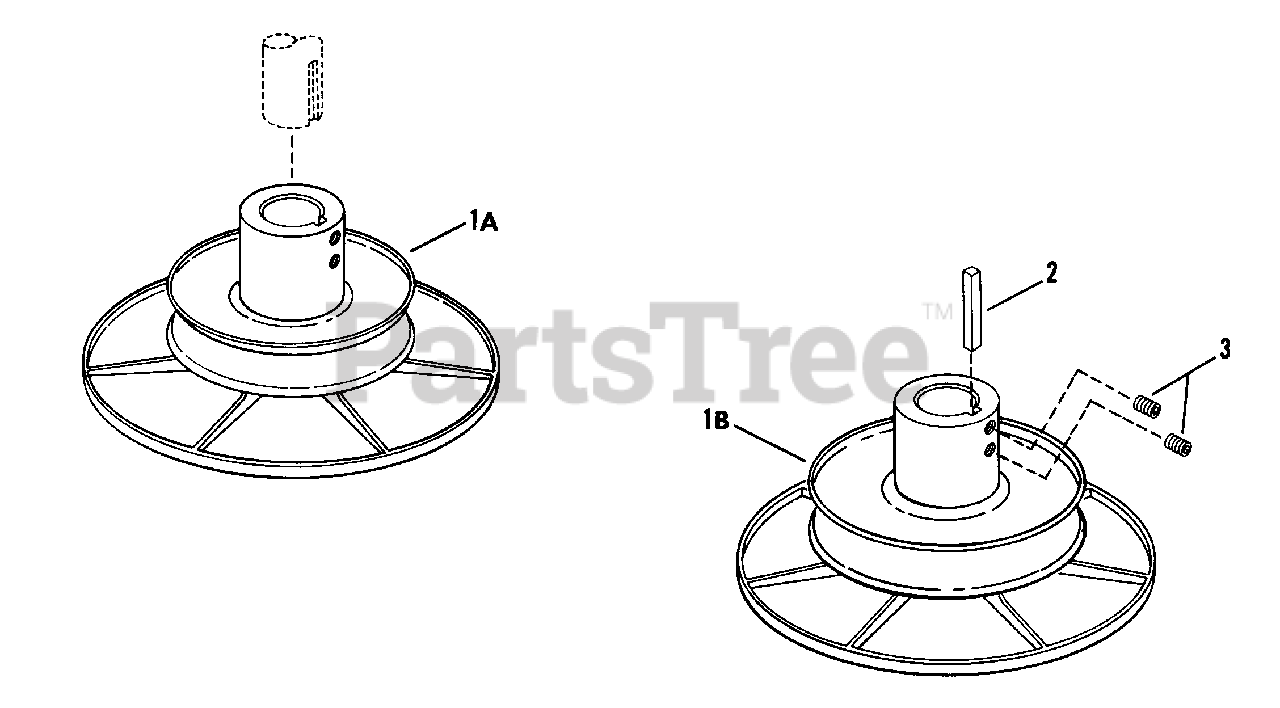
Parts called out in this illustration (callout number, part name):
1A	ASSEMBLY, Drive Disc, 4" O.D. for 30 & 33" Models
1B	ASSEMBLY, Drive Disc, 5" O.D. for 28 & 41" Models
2	KEY, 1/4x1/4x2"
3	SET-SCREW, 3/8-16x3/8"
